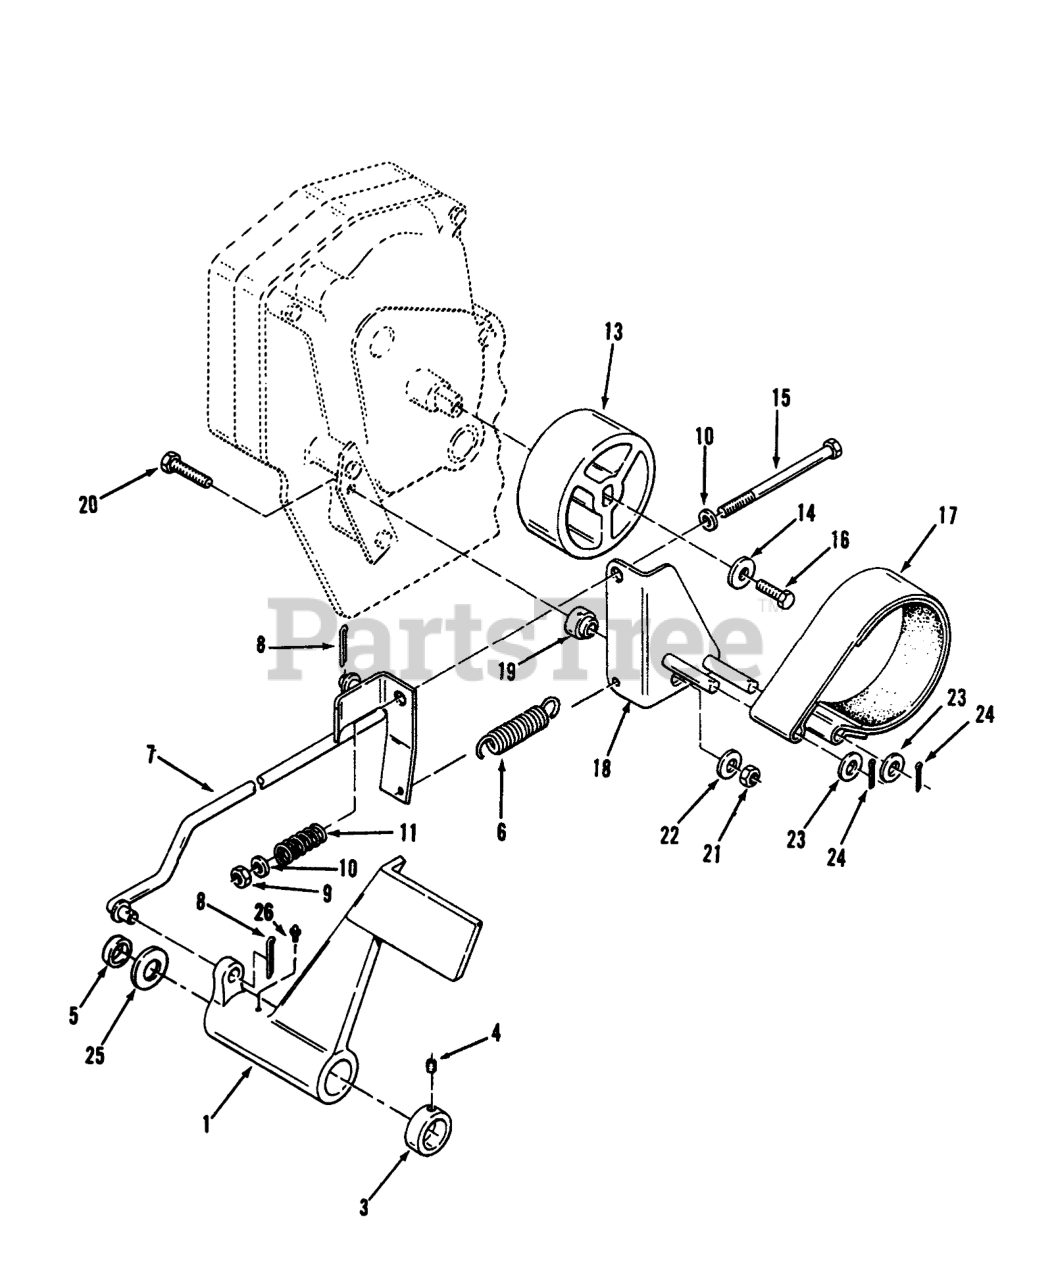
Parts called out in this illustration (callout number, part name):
1	Pedal-Brake
3	COLLAR
4	SCREW-HSH
5	SPACER-OUTER
6	SPRING
7	ASY BRAK RD WAR
8	PIN-COTTER
9	NUT-LOCK, NI
10	WASHER-FLAT
11	SPRING-COMPRESSION
13	DRUM-BRAKE
14	WASHER
15	SCREW-HH
16	SCREW-HH, LOCK
17	ASSY-BRAKE BAND
18	WA-BRAKE PIVOT B
19	BUSHING-BRAKE PIVOT
20	SCREW-HH
21	NUT-LOCK, NI
22	WASHER-FLAT
23	WASHER-FLAT
24	PIN-COTTER
25	WASHER
26	FITTING-GREASE
